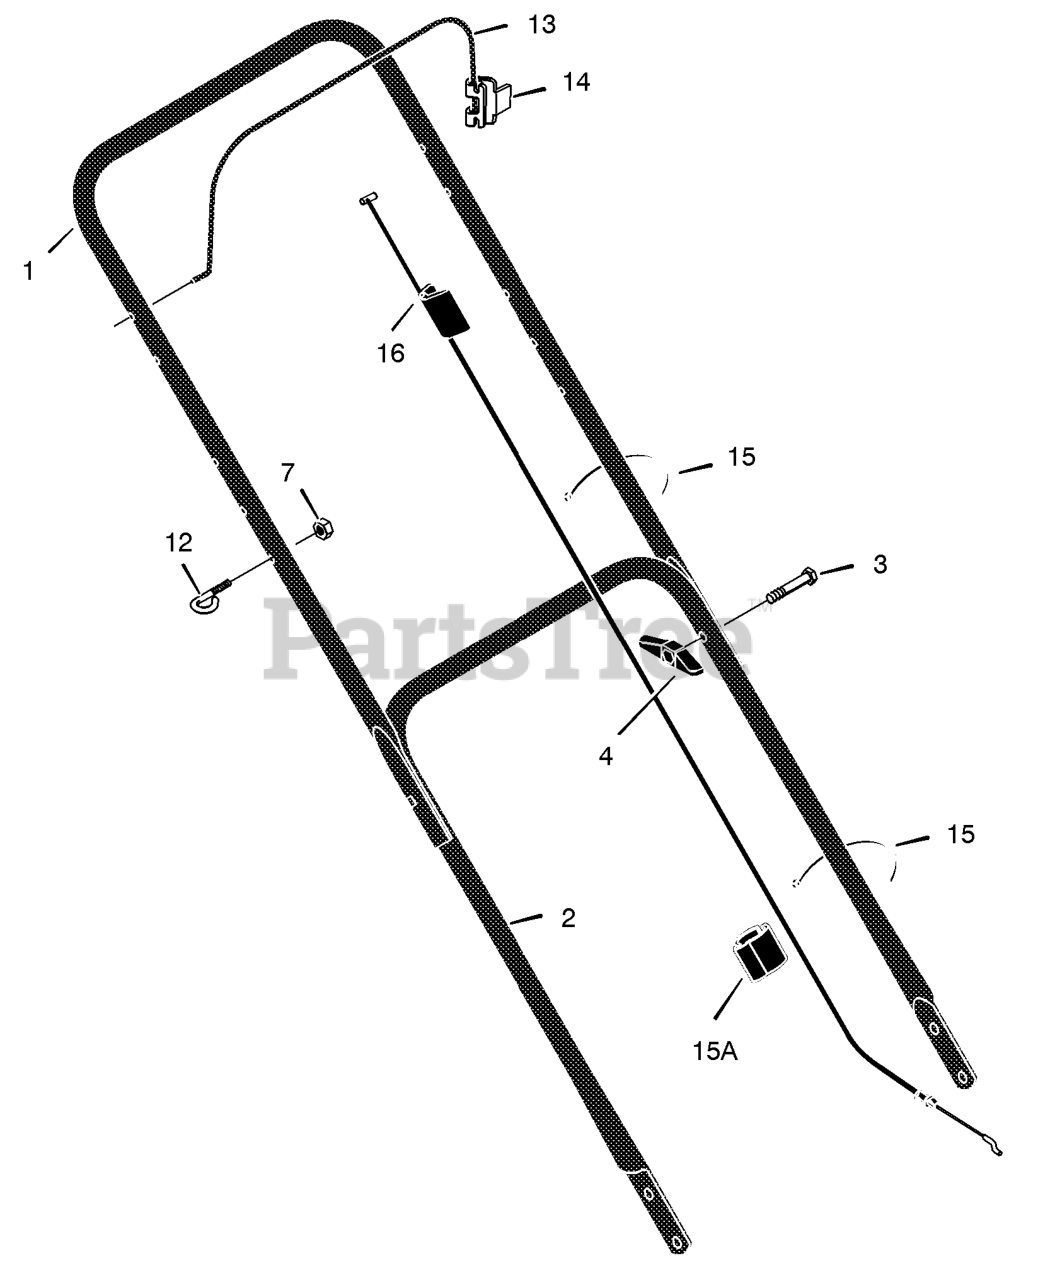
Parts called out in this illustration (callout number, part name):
1	Handle, Upper (Black)
2	Handle, Lower (Black)
4	Knob, Plastic
7	Locknut
12	Guide, Rope
13	Engine Stop Lever
14	Bracket, Stop Lever
15	Tie Strap, Cable
15A	Fastener, Cable
16	Engine Stop Cable
